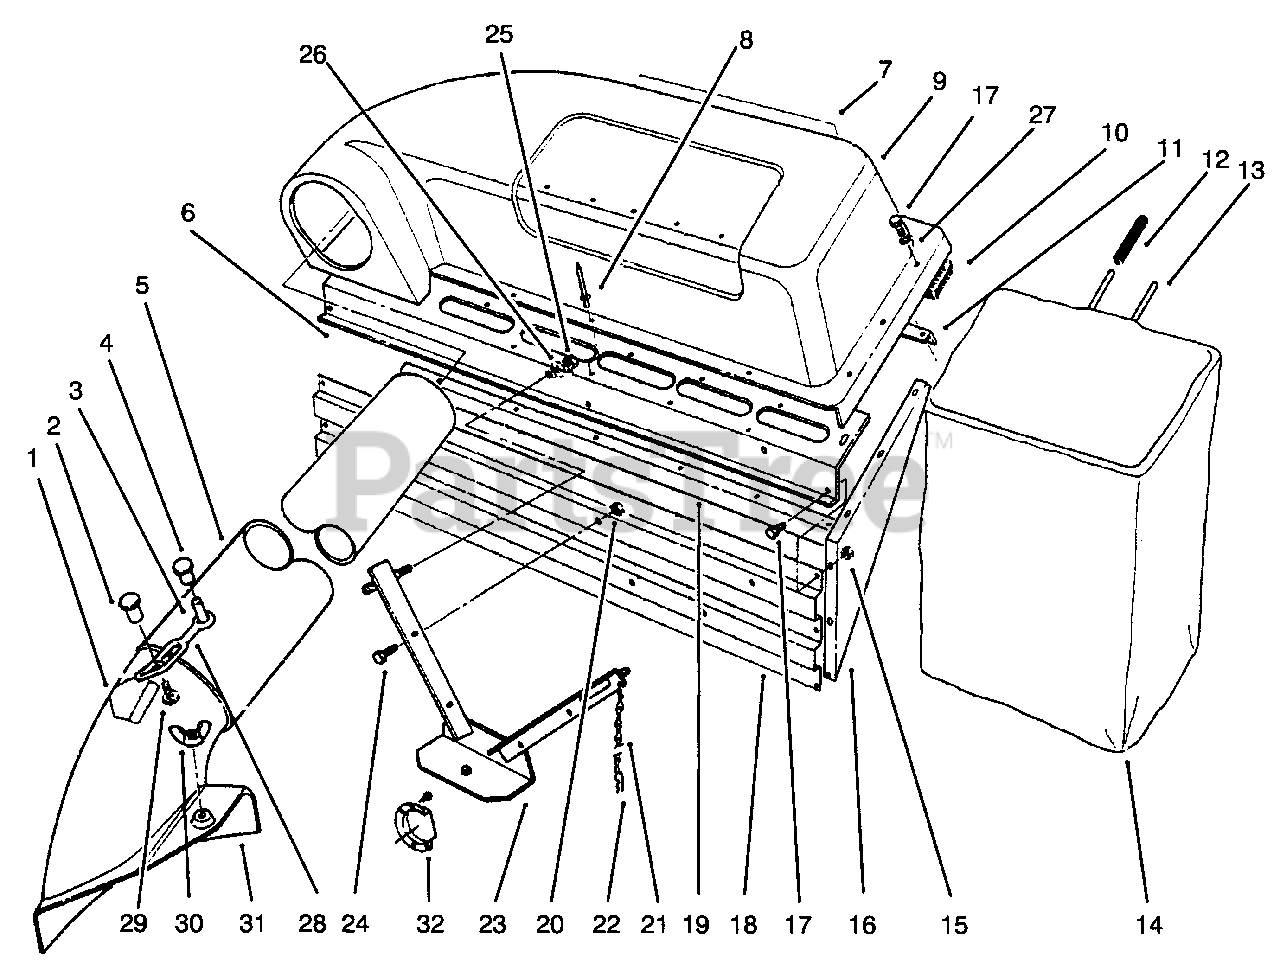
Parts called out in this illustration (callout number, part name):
1	Decal-Chute
4	Fastner-Panel
7	Decal-Twin Bagger
8	Rivet-Pop
10	Seal-Foam
11	Bracket-Frame, Bag
12	Grip-Handle
13	Frame-Bag
15	Nut-Lock
16	Plate-Side
17	Screw-Cap Hex. Hd.
18	Shield-Muffler
19	Channel-Support, Bag
20	Nut-Lock
22	Pin-Hair, Cotter
23	V-Bracket
24	Screw-Cap Hex. Hd.
25	Nut-Lock
26	Washer-Flat
27	Washer-Flat
28	Retainer-Duct
31	Assembly-Chute (Incl. Ref. #1, 2 & 29)
32	Deflector-Muffler
